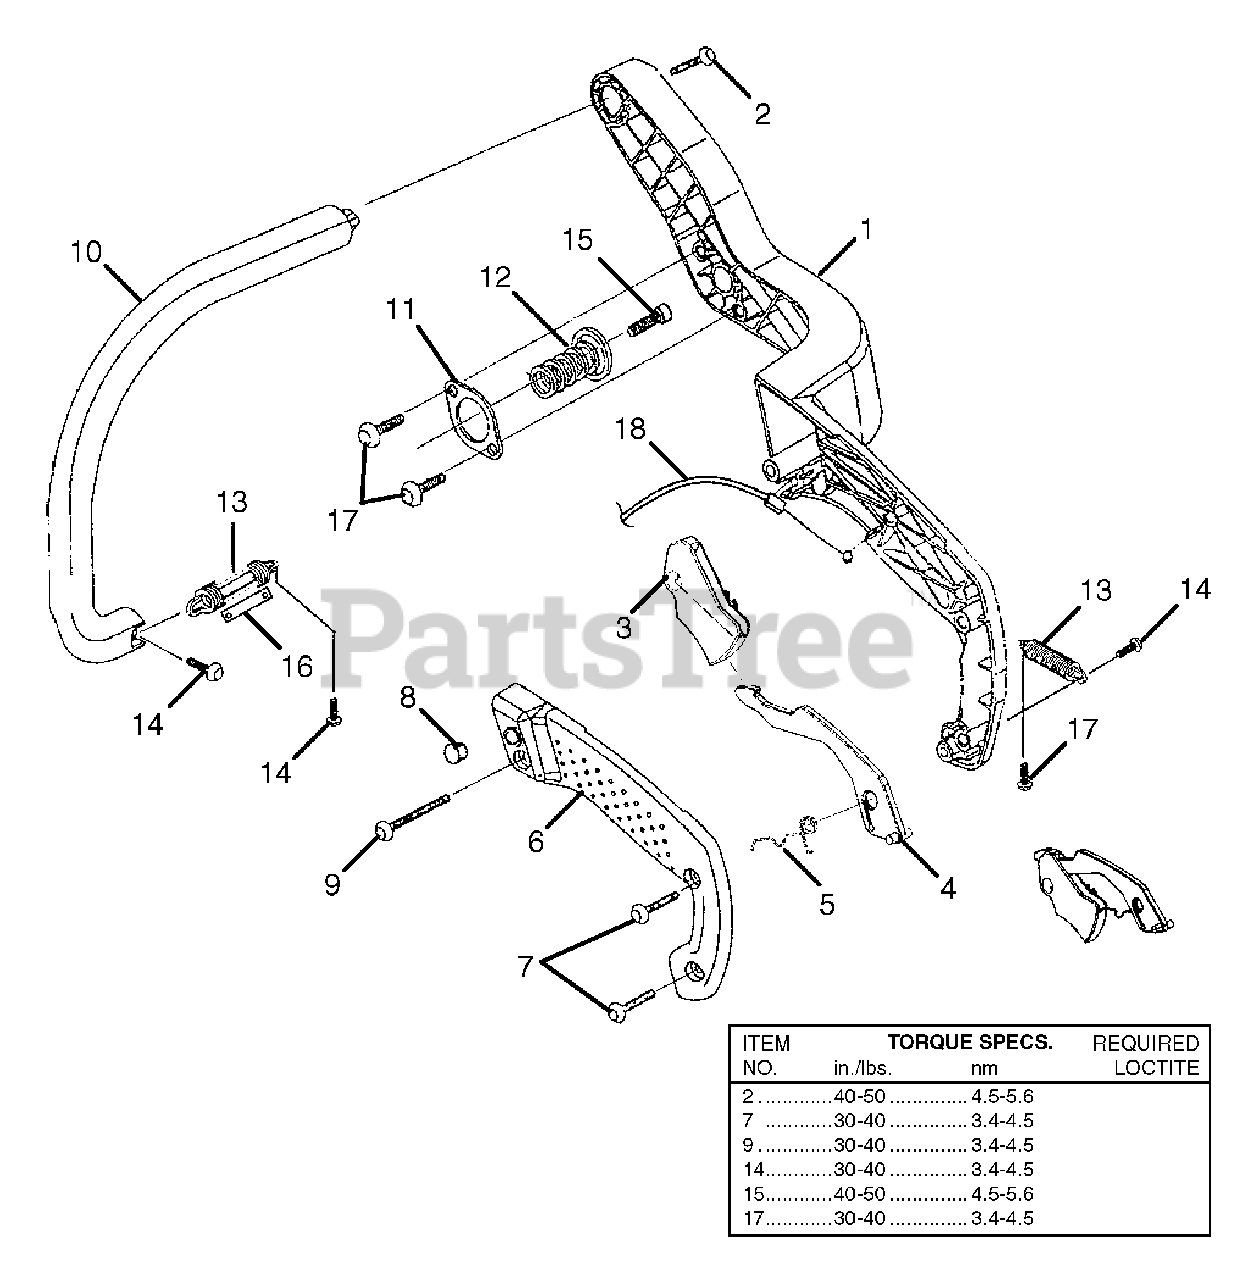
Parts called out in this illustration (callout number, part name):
1	REAR HANDLE
2	SCREW (12-14 x 1-1/2 in.)
3	TRIGGER, THROTTLE
4	THROTTLE LOCK OUT
5	TORSION SPRING
6	HANDLE COVER
7	SCREW (10-14 x 3/4 in.)
8	PLUG-PLASTIC
9	SCREW (10-14 x 1-3/8 in.)
10	FRONT HANDLE KIT
11	ISOLATOR PLATE
12	UPPER ISOLATION SPRING
13	SPRING - ISOLATOR
14	SCREW (10-14 x 5/8 in.)
15	SCREW (10-24 x 5/8 in.)
16	SPRING RETAINER
17	SCREW (10-14 x 1/2 in.)
18	THROTTLE CABLE
